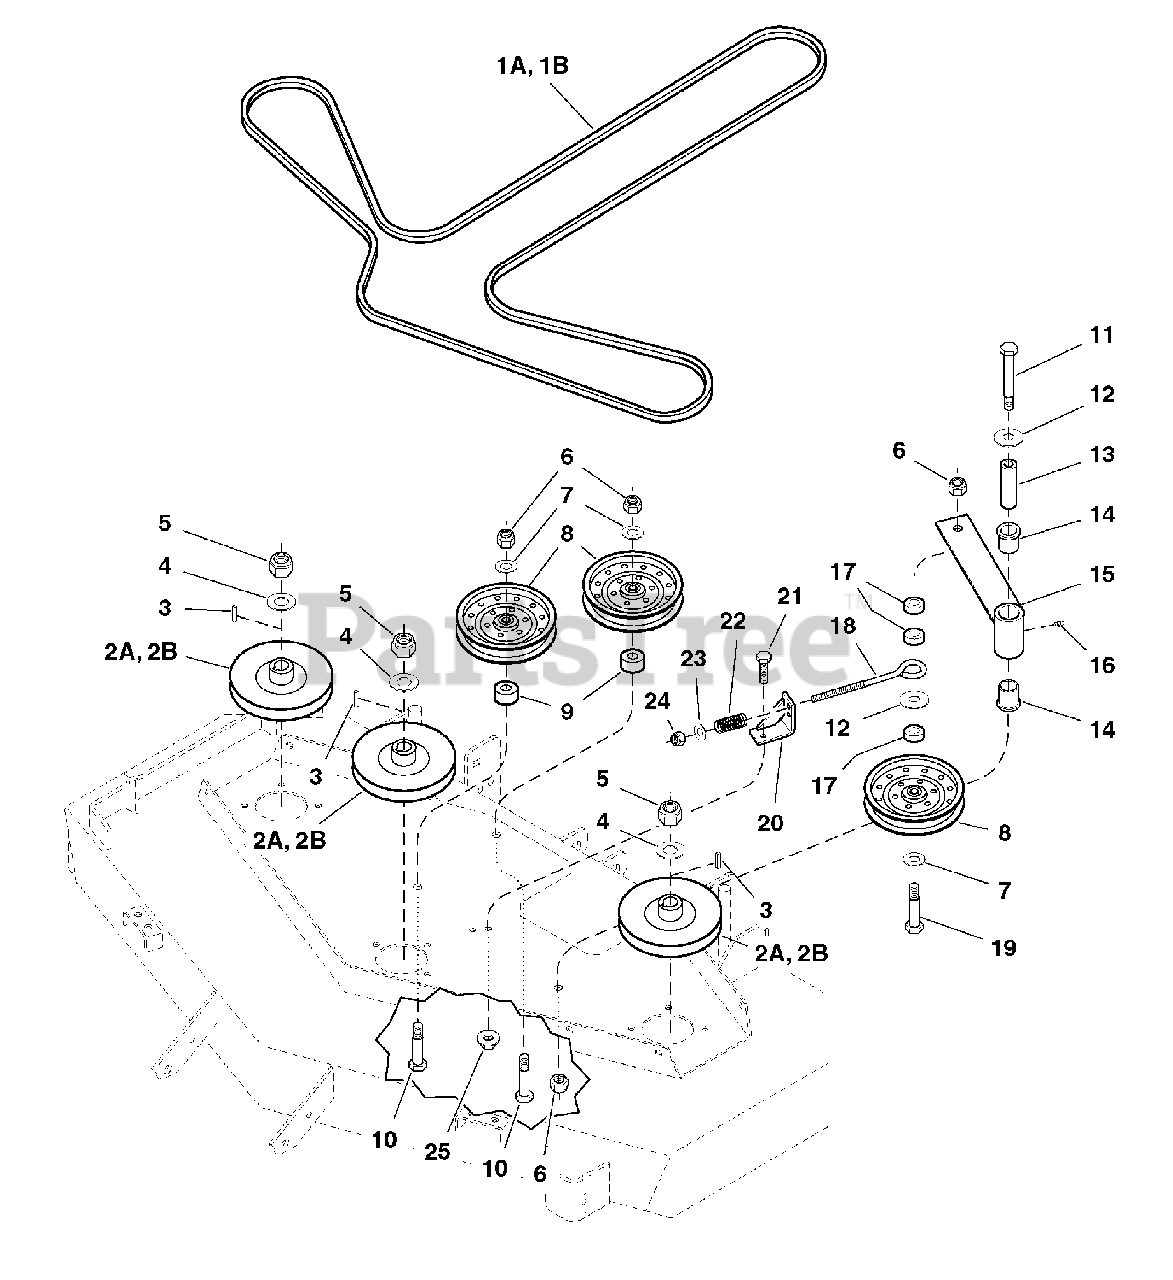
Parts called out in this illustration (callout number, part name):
1A	BELT (48" Deck)
1B	BELT, 5V-SEC, 150.9" EL, LRG ARAMID, WRPD, RC (52" Deck)
2A	PULLEY, Spindle (48" Deck)
2B	PULLEY, Spindle (52" Deck)
3	KEY, 1/4" x 1-1/4"
4	WASHER, Spring
5	NUT, Hex, Nylon Lock, 5/8-18
6	NUT, Hex, Nylon Lock, 1/2-13
7	WASHER, 1/2
8	*PULLEY, FLAT IDLER, 6-3/4"
9	SPACER, Idler Pulley
10	CAPSCREW, Hex Hd, 1/2-13 x 3
11	CAPSCREW, Hex Hd, 1/2-13 x 4-1/2
12	WASHER, USS, 1/2
13	IDLER ARM PIVOT SHAFT
14	BUSHING, Flange
15	IDLER ARM
16	GREASE FITTING
17	SPACER, Idler
19	CAPSCREW, Hex Hd, 1/2-13 x 3-1/2
20	SPRING ANCHOR
21	CAPSCREW, Hex Hd, 3/8-16 x 1
22	SPRING, Compression, 2"
23	WASHER, 3/8
24	NUT, Hex, Nylon Lock, 3/8-16
25	NUT, Hex, Serrated Flange, 3/8-16
